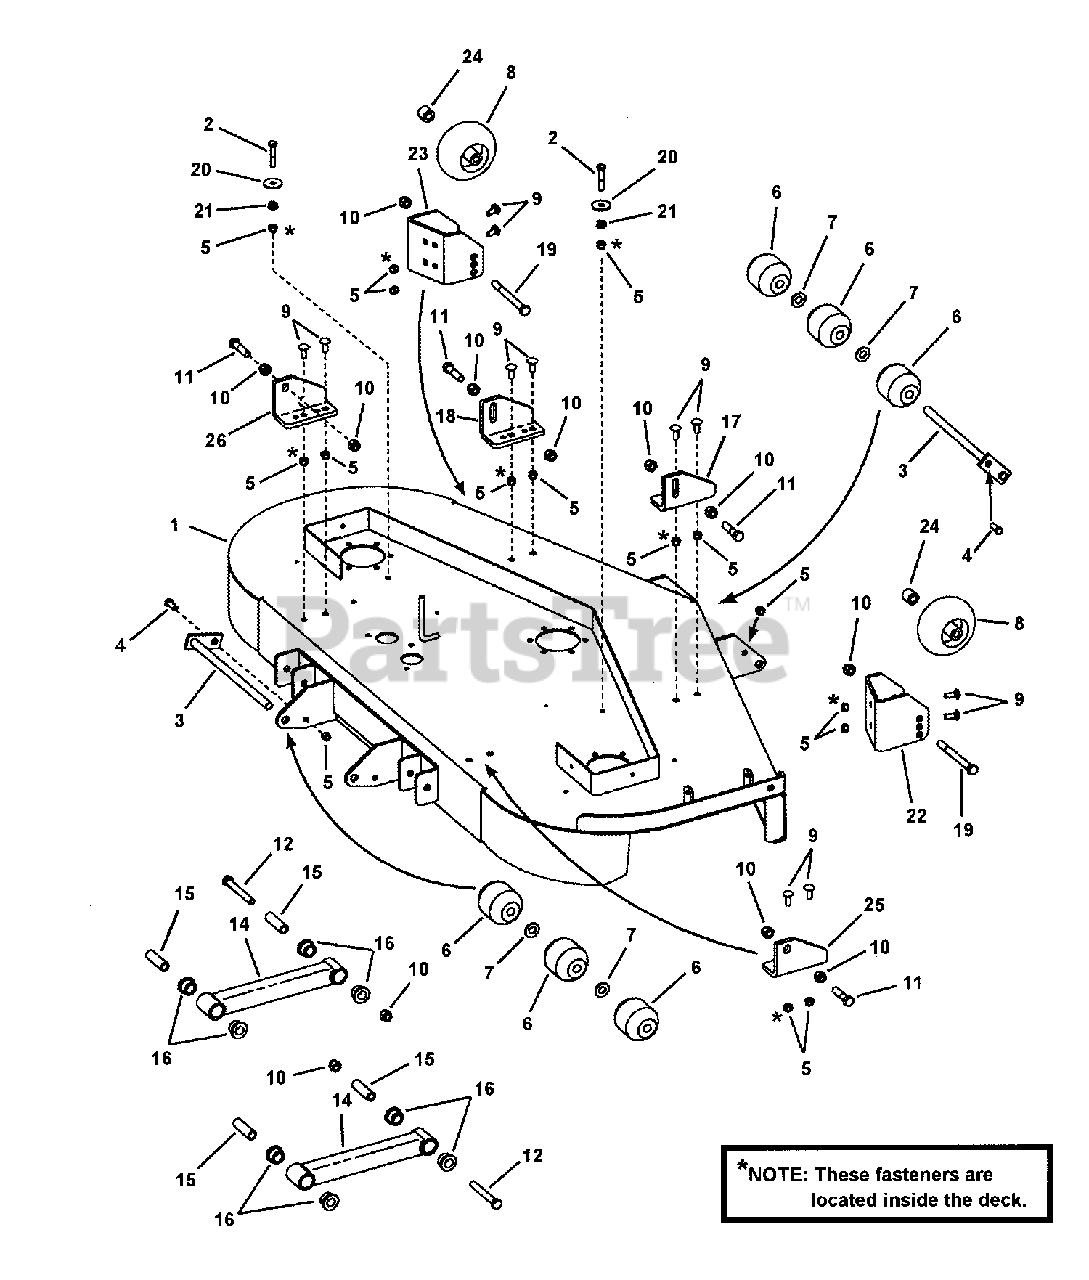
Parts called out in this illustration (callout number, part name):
1	WELDMENT, 61" Deck
2	BOLT, 3/8-16 X 2, GD5, CZ
3	WELDMENT Pivot Pin
4	BOLT, 3/8-16 X 1" GD5 CZ
5	NUT, 3/8-16 HEX NYLON LOCK
6	ROLLER Low Density Polyethylene
7	WASHER, 5/8" Flat SAE
8	GAUGE WHEEL, Polyethylene
9	BOLT, 3/8-16 x 1" Square Neck Carriage GR 5
10	NUT, 1/2-13 HEX NYLON LOCK
11	SCREW, 1/2-13 x 2" Hex Head Cap, GR 5
12	BOLT, 1/2-13 x 3-3/4" Hex Head Cap, GR 5
14	WELDMENT, Pusher Bar
15	SLEEVE - Suspension
16	BUSHING - Suspension
17	BRACKET, Deck Lift, RH Front
18	BRACKET, Deck Lift, LH Front
19	BOLT, 1/2-13 X 5 GD5 YZ
20	WASHER, .406 x 1.50 x .120 Flat
21	NUT, 3/8-16 HEX SERRATED FLANGE
22	WHEEL BRACKET Front Right
23	WHEEL BRACKET Front Left
24	SPACER, Gauge Wheel
25	BRACKET, Deck Lift, RH Rear
26	BRACKET, Deck Lift, LH Rear
